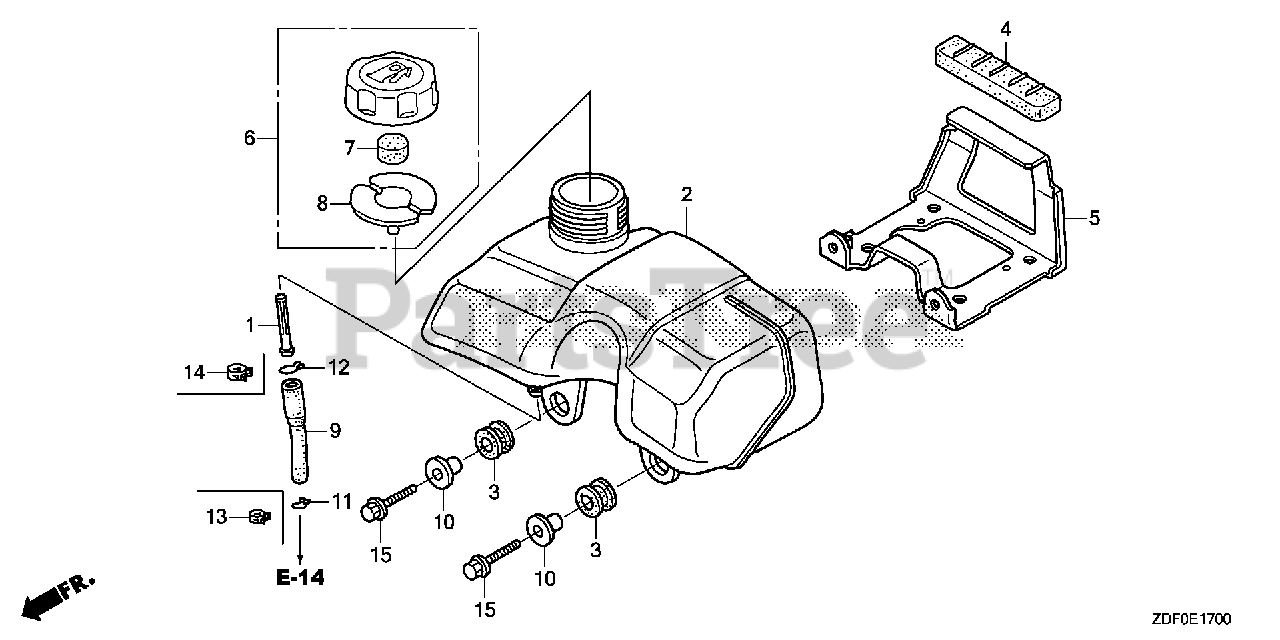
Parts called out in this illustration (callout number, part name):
1	FILTER, FUEL
2	TANK, FUEL
3	RUBBER A, TANK MOUNTING
4	RUBBER B, TANK MOUNTING
5	STAY, FUEL TANK
6	CAP ASSY., FUEL TANK
7	SPONGE, FUEL CAP BREATHER
8	GASKET, FUEL CAP
9	TUBE A, FUEL (FKM)
10	COLLAR, CANISTER MOUNTING
13	CLIP, TUBE (D8)
14	CLIP, TUBE (10.5MM)
15	BOLT, FLANGE (6X20)
